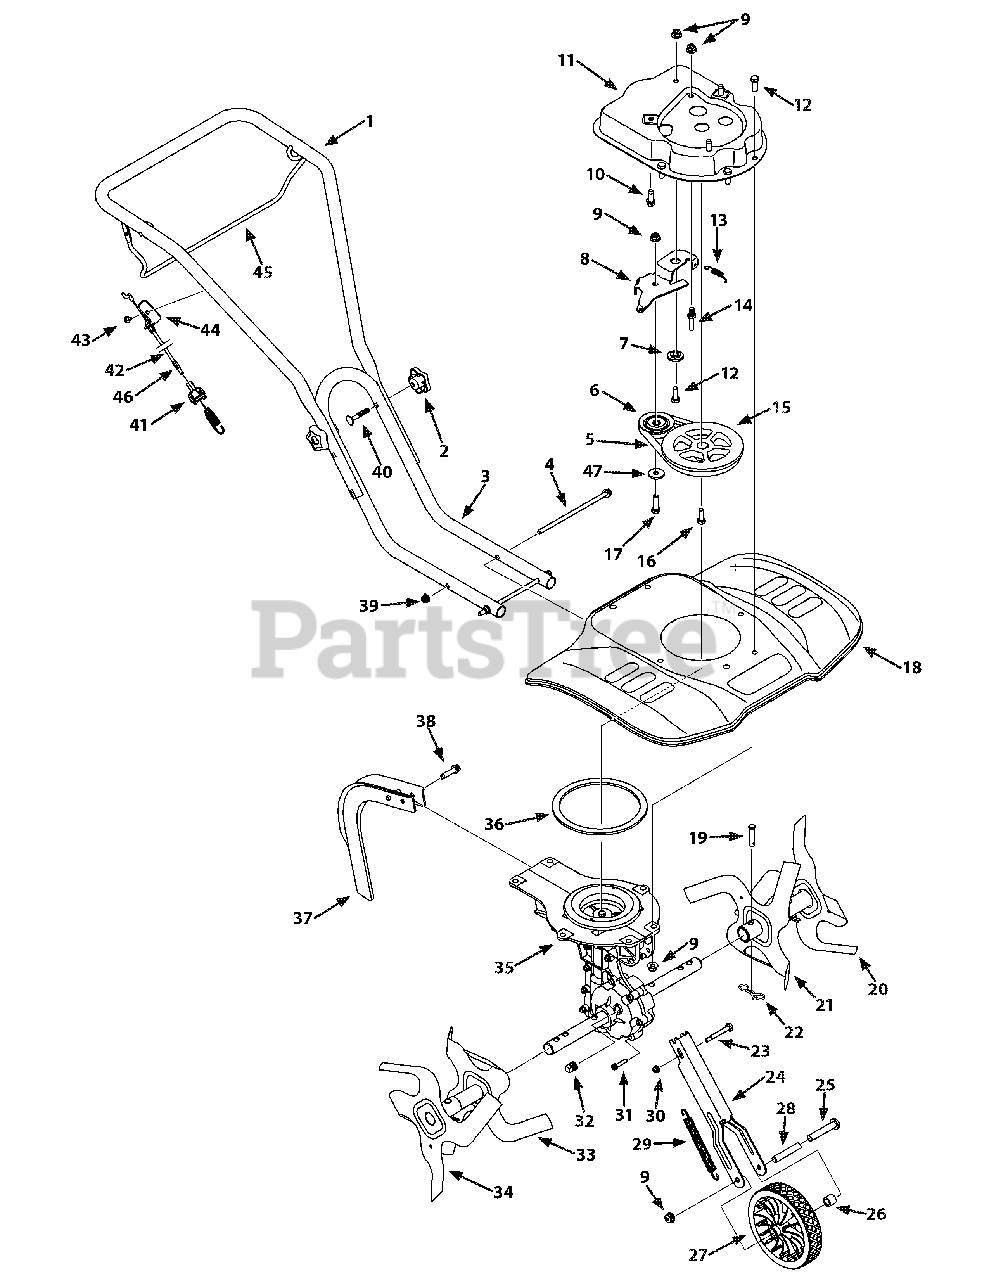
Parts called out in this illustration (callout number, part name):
1	Upper Handle
2	Star Handle Knob
3	Lower Handle
4	Flange Screw: 5/16-18:7.5:GR5
5	V-Belt
6	Idler Pulley
7	Shoulder Spacer
8	Idler Bracket
9	Flange Lock Nut: 3/8-16
10	TT Screw: 3/8-16:1.00
11	Belt Cover
12	HH Cap Screw: 3/8-16:1.00
13	Extension Spring
14	Stud: 33 x 1.5: 3/8-16
15	Flywheel Pulley
16	HH Cap Screw: 3/8-24:1.00
17	HH Cap Screw: 3/8-16:1.55
18	Tine Shield 61 cm
19	Clevis Pin
20	Outer Tine Assembly LH
21	Inner Tine Assembly LH
22	Cotter Pin, Bow Tie
23	Shoulder Screw: .31x2:1/4-20
24	Front Wheel Bracket
25	HH Cap Screw: 3/8-16:3.00
26	Spacer
27	Wheel 7x1.5 Star-Diam
28	Sleeve
29	Extension Spring
30	Flange Lock Nut: 1/4-20
31	TT Screw: 1/4-20:1.25
32	Pipe Plug: 3/8 NPT
33	Inner Tine Assembly RH
34	Outer Tine Assembly RH
35	Case Assembly
36	Gasket
37	Depth Stake Assembly
38	TT Screw: 3/8-16:1.50
39	Flange Lock Nut: 5/16-18
40	Carriage Bolt
41	Clutch Cable Fitting
42	Clutch Cable
43	TT Screw: 1/4-20:.50
44	Cable Mount Bracket
45	Clutch Bail
46	Retaining Ring
47	Flat Washer, .406 x .875 x .059
